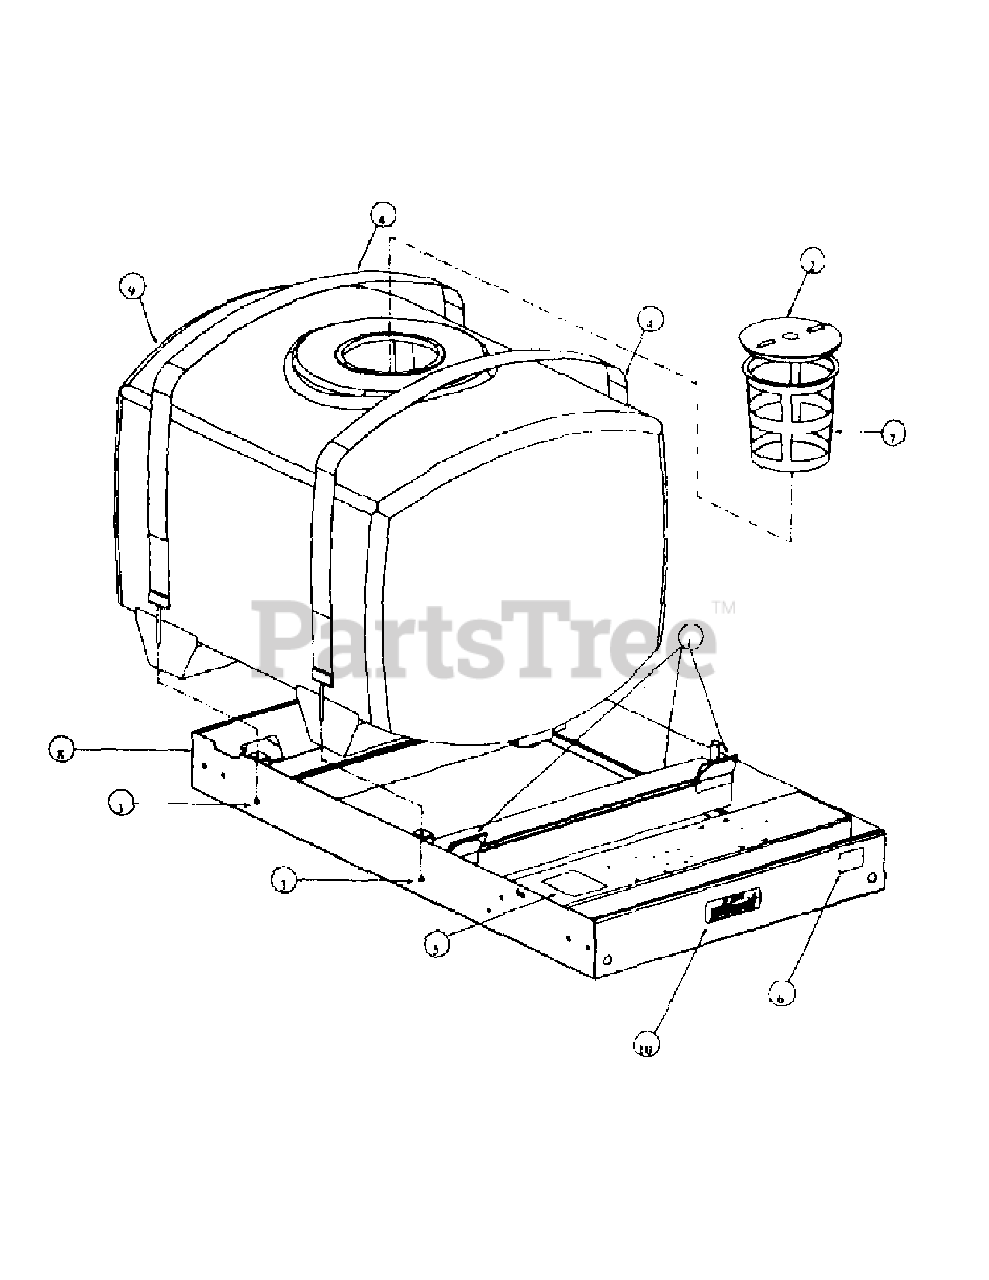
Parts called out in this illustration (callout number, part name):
1	Foam, Adhesive Backed, 4" x 1/4" by ft.
2	Tank, Lid
3	Nut, Nylock 5/16 - 18
4	Tank Strap Assembly
5	Decal Safety Procedures
6	Decal "Made in America"
7	Strainer Basket, 10"
8	Main Frame Assembly
9	200 Gallon Tank Assembly
10	Decal, "Sy 200PE", 2-1/4" x 7"
